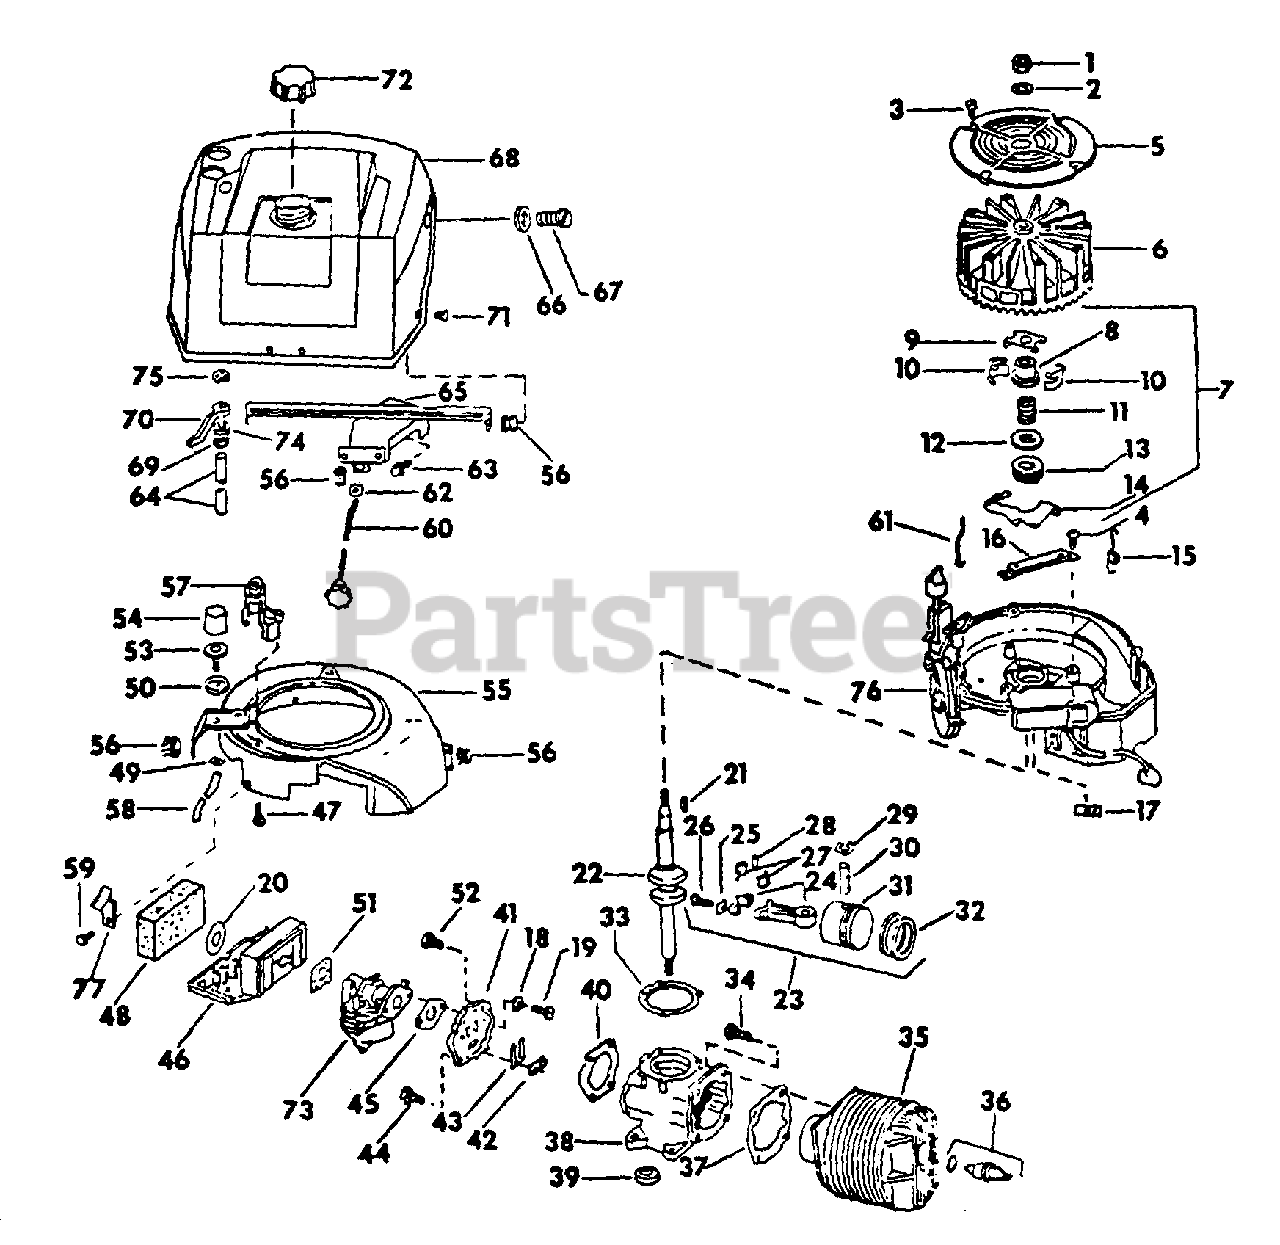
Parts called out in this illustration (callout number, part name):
1	NUT, 7/16-20 HEX.
2	WASHER, 7/16 ZND INT TOOTH LOCK
3	SCREW, 10-24 X 1/2 TRUSS-HD REC TAP.
4	SCREW, 5/16-18 X 1-3/8 ZND HEX-HD CAP
5	SCREEN, FLYWHEEL
7	GOVERNOR ASSY
8	COLLAR, GOVERNOR
9	YOKE, GOVERNOR
10	WEIGHT, GOVERNOR
11	SPRING, GOVERNOR
12	WASHER, THRUST
13	COLLAR, THRUST
14	LEVER, GOVERNOR
15	SPRING, VARIABLE SPEED
16	BRACKET, GOVERNOR LEVER
21	KEY, CRANKSHAFT
23	PISTON & CONNECTING ROD ASSY
24	ROD ASSY, CONNECTING
25	LOCKPLATE, SCREW
26	SCREW, CONNECTING ROD
27	LINER, CONNECTING ROD
28	BEARING SET, NEEDLE
29	RING, RETAINING
32	RING SET, PISTON - 2 RINGS
33	GASKET, CRANKCASE TO ARM PLATE .010
34	SCREW, CYL TO CRANKCASE
36	SPARK PLUG & GASKET
37	GASKET, CYL TO CRANKCASE
38	CRANKCASE & SEAL ASSY
40	GASKET, REED PLATE
41	REED PLATE ASSY
42	PLATE, BACKUP
44	SCREW, HH REED PLATE TO CRANKCASE
45	GASKET, CARBURETOR
46	FILTER ASSY, AIR
48	ELEMENT, FILTER
52	SCREW, HH REED PLATE TO CRANKCASE
54	BULB, PRIMER
55	BAFFLE AND BRACKET
57	BRACKET & EYELET
61	ROD, GOVERNOR
65	BRACKET, SHROUD
68	SHROUD, TANK & VALVE ASSY
69	CLIP, SPRING
71	SCREW, COVER MTG
73	CARBURETOR ASSY
76	MAGNETO ASSY
77	GUIDE, ROPE
